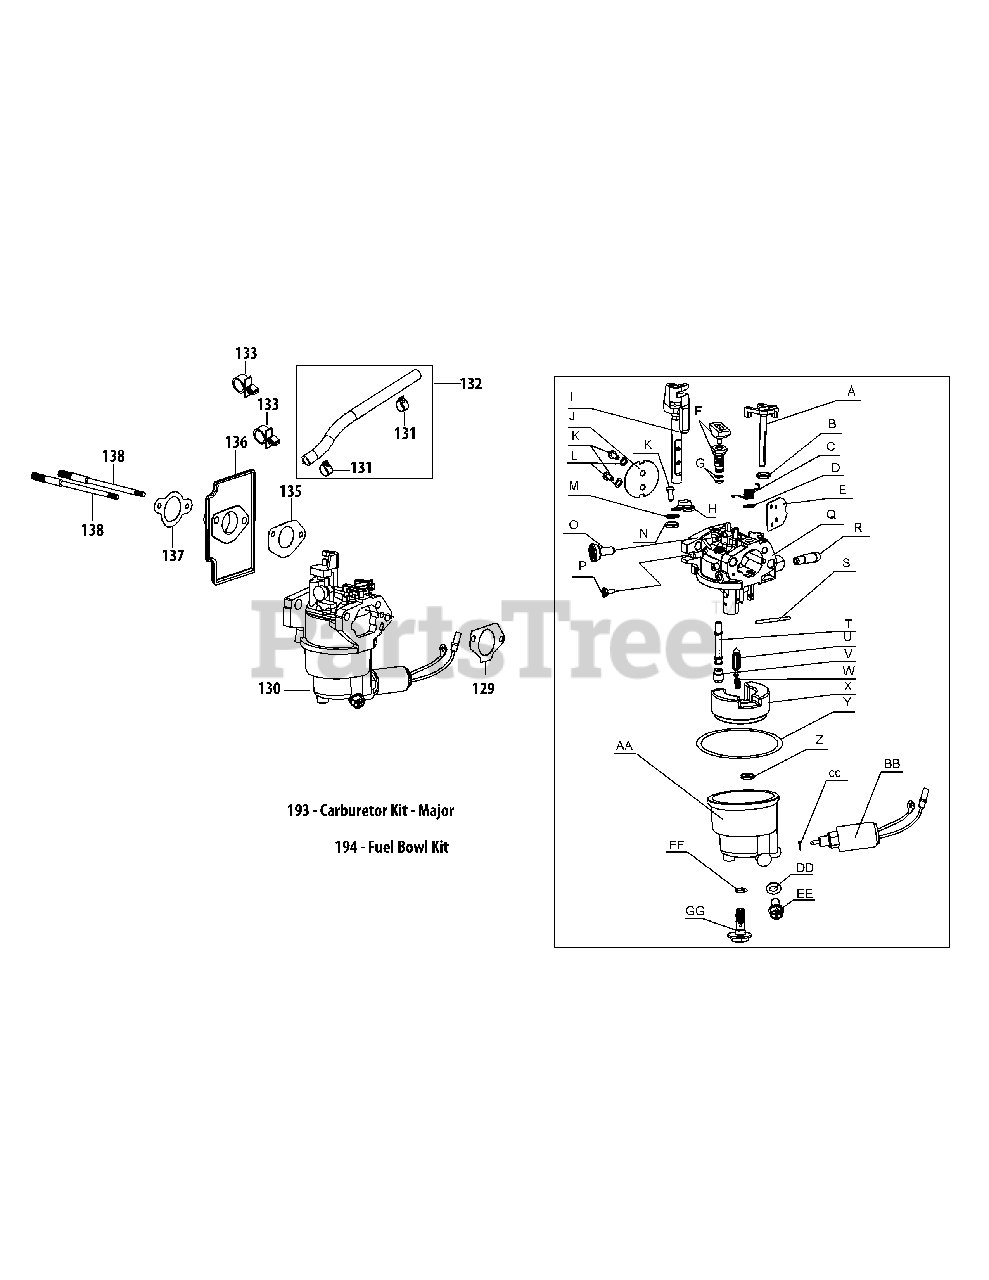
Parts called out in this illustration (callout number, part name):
129	Manifold Gasket/Add Air Hole
130	Carburetor Assembly (Hy-4P90F)
131	Fuel Hose Clamp
132	Fuel Line Kit
133	Plastic Support Clamp
135	Carburetor Gasket
136	Carburetor Insulator
137	Carburetor Insulator Gasket
193	Carburetor Kit - Major
194	Fuel Bowl Kit
A	Choke Shaft
B	Choke Shaft Fiber O-Ring
C	Choke Return Spring
D	Flat Steel Washer
E	Choke Plate
F	Idle Jet Assembly
G	Idle Jet O-Ring
H	Sheetmetal Housing
I	Throttle Shaft
J	Throttle Plate
L	Lock Washer
M	Nylon/Plastic O-Ring
N	Fiber O-Ring
O	SPEED IDLE SCREW
P	Idle Mixture Screw
Q	Carburetor Body
R	Fuel Inlet
S	HINGE FLOAT PIN
T	Emulsion Tube
U	NEEDLE VALVE
V	Main Jet
W	NEEDLE VALVE SPRING
X	CARBURETOR FLOAT
Y	FUEL BOWL O-RING
Z	Square-Ring
AA	FLOAT BOWL
BB	FUEL SOLENOID
CC	Solenoid Valve Washer
DD	FUEL DRAIN PLUG GASKET
EE	FUEL DRAIN PLUG
FF	O-Ring
GG	FUEL BOWL BOLT
